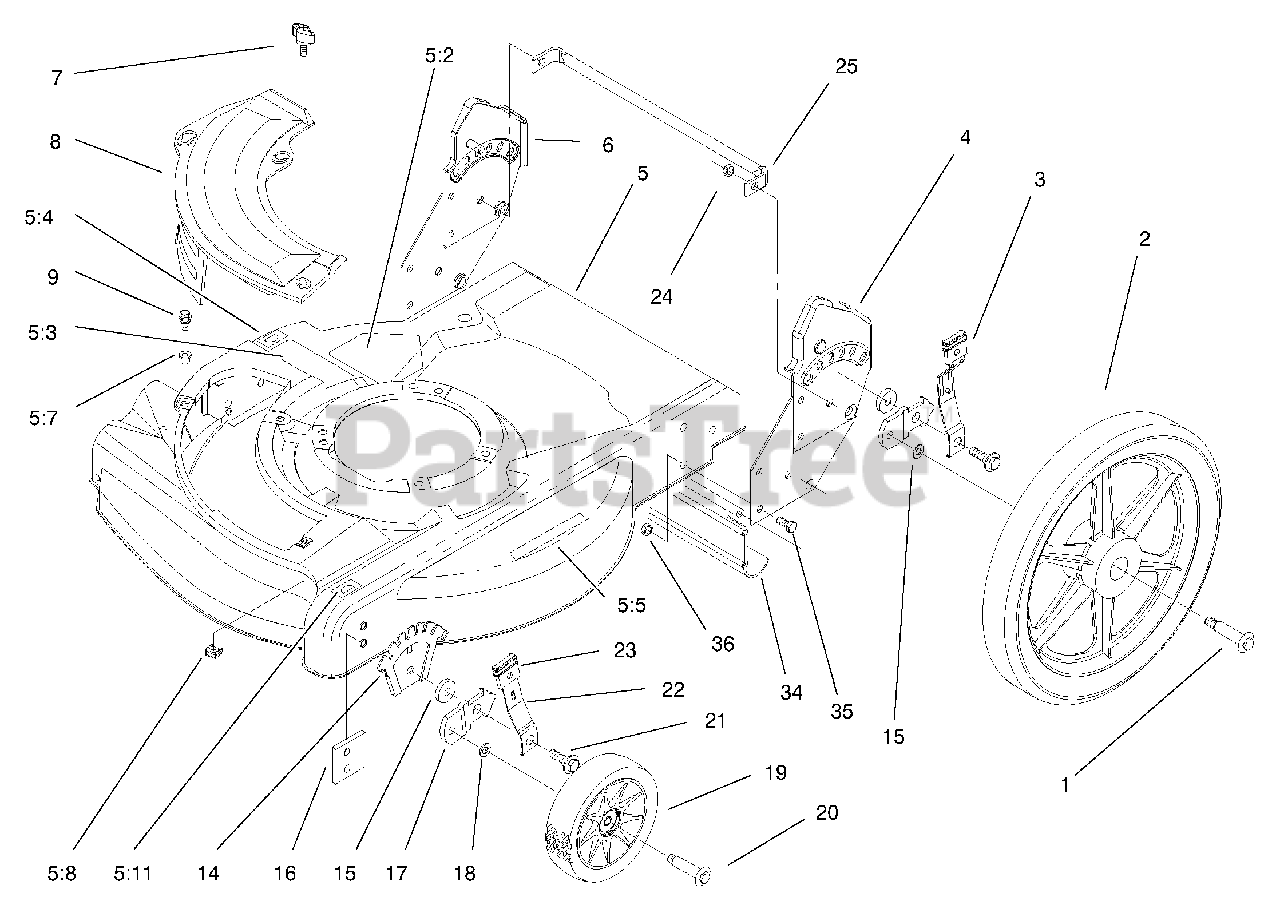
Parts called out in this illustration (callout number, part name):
1	SHOULDER BOLT
3	SPRING ARM ASM
4	Assy-Bracket Handle,LH
5	HOUSING ASM
5:2	DECAL-DANGER
5:3	DECAL - WARNING
5:4	DECAL - HOC, RH
5:5	DECAL-WARNING
5:7	GROMMET - PLASTIC
5:8	NUT-CAGE
5:11	DECAL - HOC, LH
6	Assy-Bracket Handle,RH
8	PLATE-MULCH
9	SCREW-SEMS
14	PLATE - HEIGHT ADJUSTMENT
15	WASHER-WHEEL
16	PLATE - BAFFLE
17	BRACKET-HEIGHT ADJUSTMENT, WHEEL
19	WHEEL & TIRE ASM
20	BOLT-SHOULDER
21	BOLT-SHOULDER
22	ARM-FRONT SPRING
23	KNOB-LEVER, HEIGHT ADJUSTMENT
24	NUT-LOCK, NI
25	BRACE-HANDLE BRACKET
34	SHIELD - TRAILING
35	SCREW-HH
36	NUT-LOCK, NI
